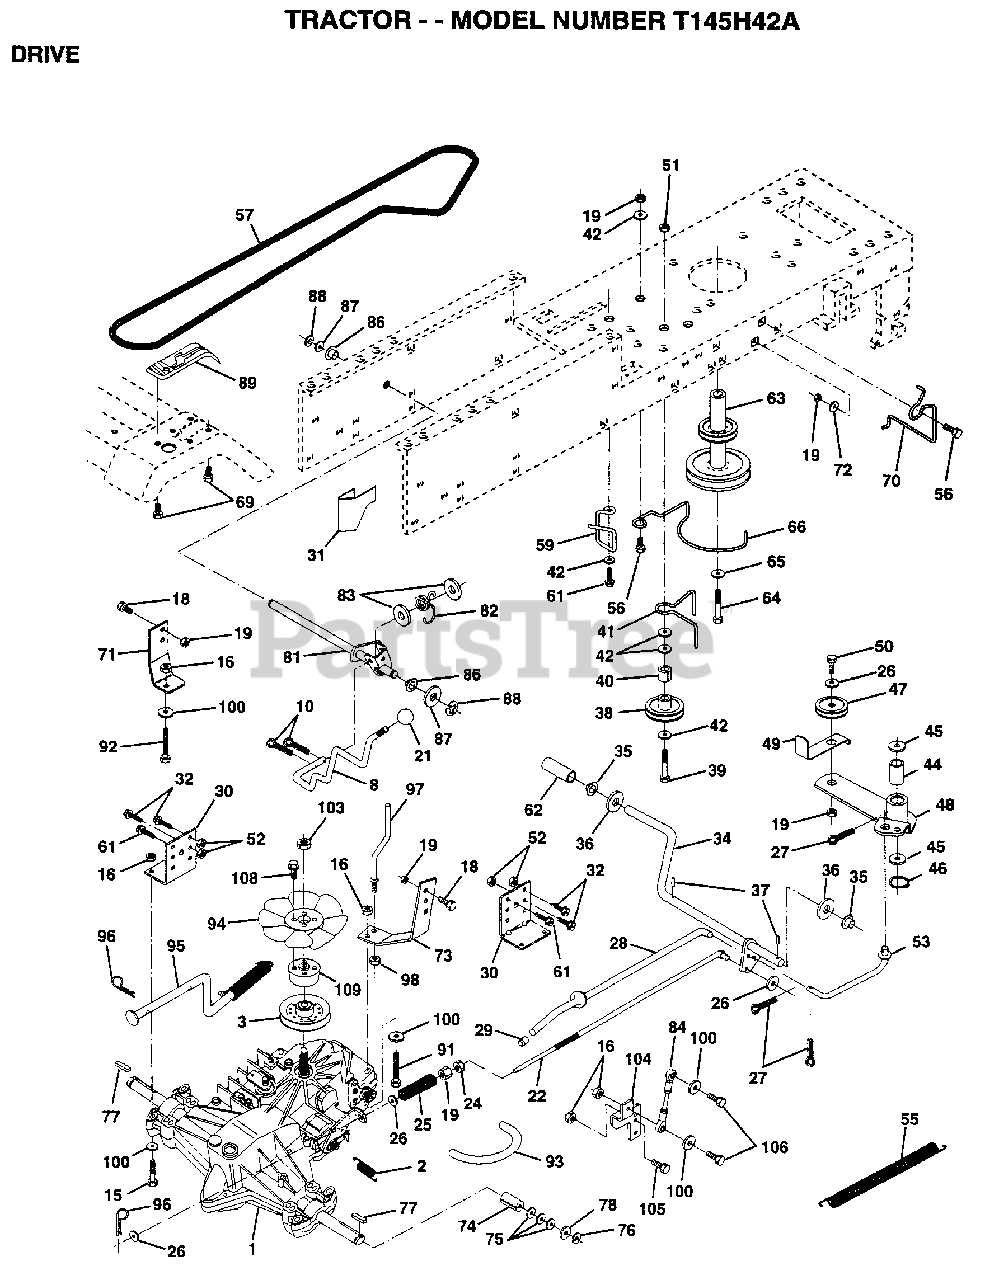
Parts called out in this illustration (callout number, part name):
1	TRANSAXLE HYD 0319-0500
2	SPRING RET BRAKE
3	PULLEY.4.20.HYDRO
8	ROD SHIFT FEND LT
10	PIN COTTER 1/8
15	BOLT HEX
16	NUT
18	BOLT
19	NUT
21	KNOB DLX BLK/BLK
22	ROD.BRAKE.HYDRO.
24	NUT
25	SPRING ROD LT
26	WASHER
27	COTTER PIN
28	ROD.BRAKE.PARK.LT
30	TRANSAXLE MTG BKT
31	"KEEPER,BELT LH T"
32	BOLT
34	SHAFT.PEDAL.FOOT
35	NYLON BEARING
36	WASHER LT
38	PULLEY.IDLER.FLAT
39	BOLT
40	SPACER T
41	BELT KEEPER LT
42	WASHER
44	"LY, BEARING"
45	WASHER LT
46	KLIP RING
48	ARM IDLER
49	RETAIN BELT
53	"LINK, CLUTCH T"
55	"SPRING, RETURN LT"
57	BELT-V.HYDR.84.61
59	KEEPER BELT CNTSP
61	SCREW
62	PEDAL COVER T
63	PULLEY.ENGINE
64	BOLT
65	LOCKWASHER
66	KEEPER.BELT.ENG.L
69	SCREW HEXWSH H-L
70	KEEPER BELT ENG
71	STRAP.TORQ.LH.HYD
72	WASHER
73	STRAP.TORQ.RH.HYD
74	SPACER SPLIT
75	WASHER
76	E-RING LT
77	SQUARE KEY
78	WASHER
81	SHAFT.CROSS.HYD
82	"SPRING,TORSION"
83	WASHER
84	ROD.TIE.BALL.HYD.
86	BUSHING
87	WASHER D
88	KLIP RING
92	HEX BOLT
93	"LINE FUEL HYD 4"""
94	"FAN 7"" HYDRO"
96	RETAINER M
97	KEEPER.BELT.RH.HY
98	NUT
100	WASHER M
104	ARM.CONTROL.PUMP
105	SCREW CAP 5/16-18
106	BOLT
108	SCREW.HXHD.10-20
109	ADAPTOR.FAN.HYDRO
